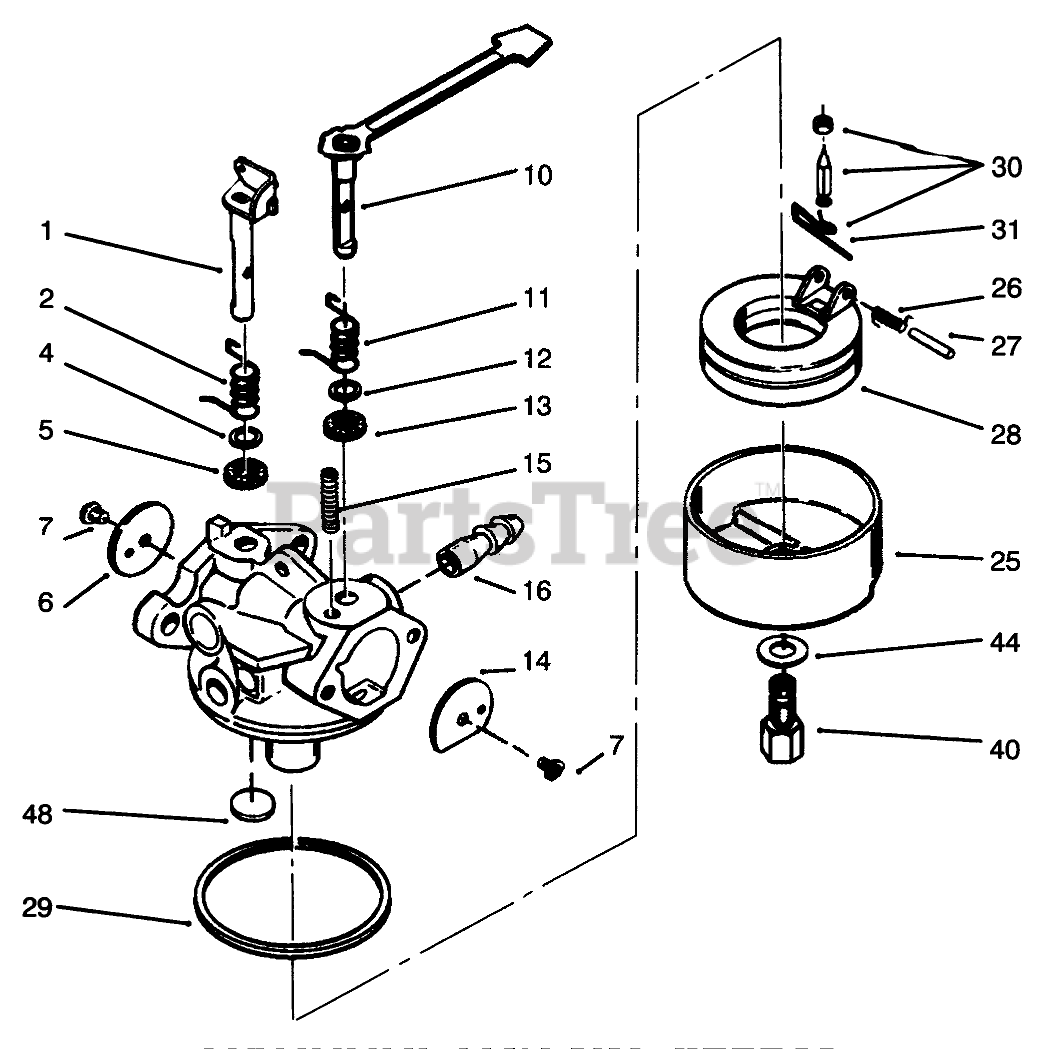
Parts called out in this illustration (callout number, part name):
1	Throttle Shaft & Lever Asm.
2	Spring-Trottle, Return
4	Dust Seat Washer
5	Seal-Dust
6	Shutter-Throttle
7	Screw-Shutter
10	Choke Shaft & Lever Asm. (Incl. Ref. #11-13)
14	Shutter-choke
15	Spring-Positioning, Choke
16	Fitting-Fuel
25	Bowl Float
26	Spring-Float, Dampening
27	Shaft-Float
28	Float
29	O Ring-Bowl, Float
30	Inlet Needle, Seat & Clip (Incl. Ref. #31)
31	Clip-Spring
40	Nut-Float Bowl
44	Gasket-Bowl
48	Plug-Welch, Atmospheric Vent
